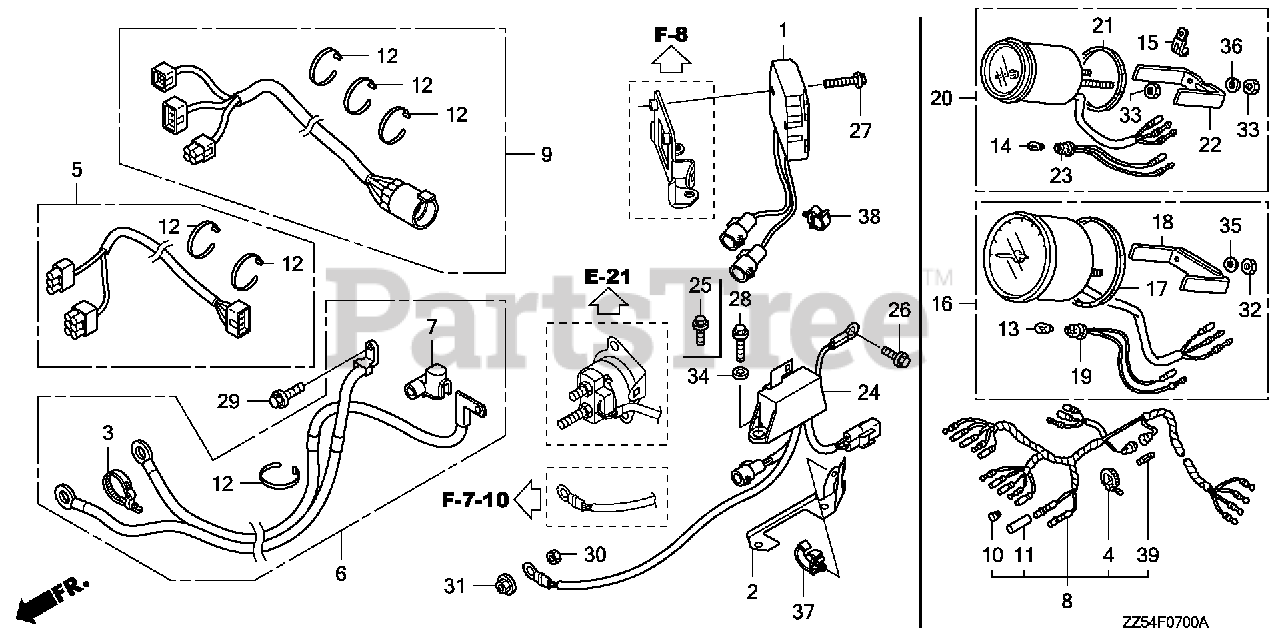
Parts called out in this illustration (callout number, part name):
1	RECTIFIER ASSY., REGULATOR
2	BRACKET A, HARNESS CLIP
3	BAND, WIRE
6	CABLE ASSY., STARTER
7	COVER, TERMINAL
12	TIE, CABLE (2.4X92) (NATURAL)
24	RELAY ASSY., POWER TILT
26	BOLT, FLANGE (6X12)
27	BOLT, FLANGE (6X25)
28	BOLT, FLANGE (6X18) (CT200)
29	BOLT, FLANGE (8X18)
30	NUT, HEX. (6MM)
31	NUT, LOCK (6MM)
34	WASHER, PLAIN (6MM)
37	CLIP, WIRE HARNESS
38	CLIP, HARNESS BAND (96.9MM) (NATURAL)
